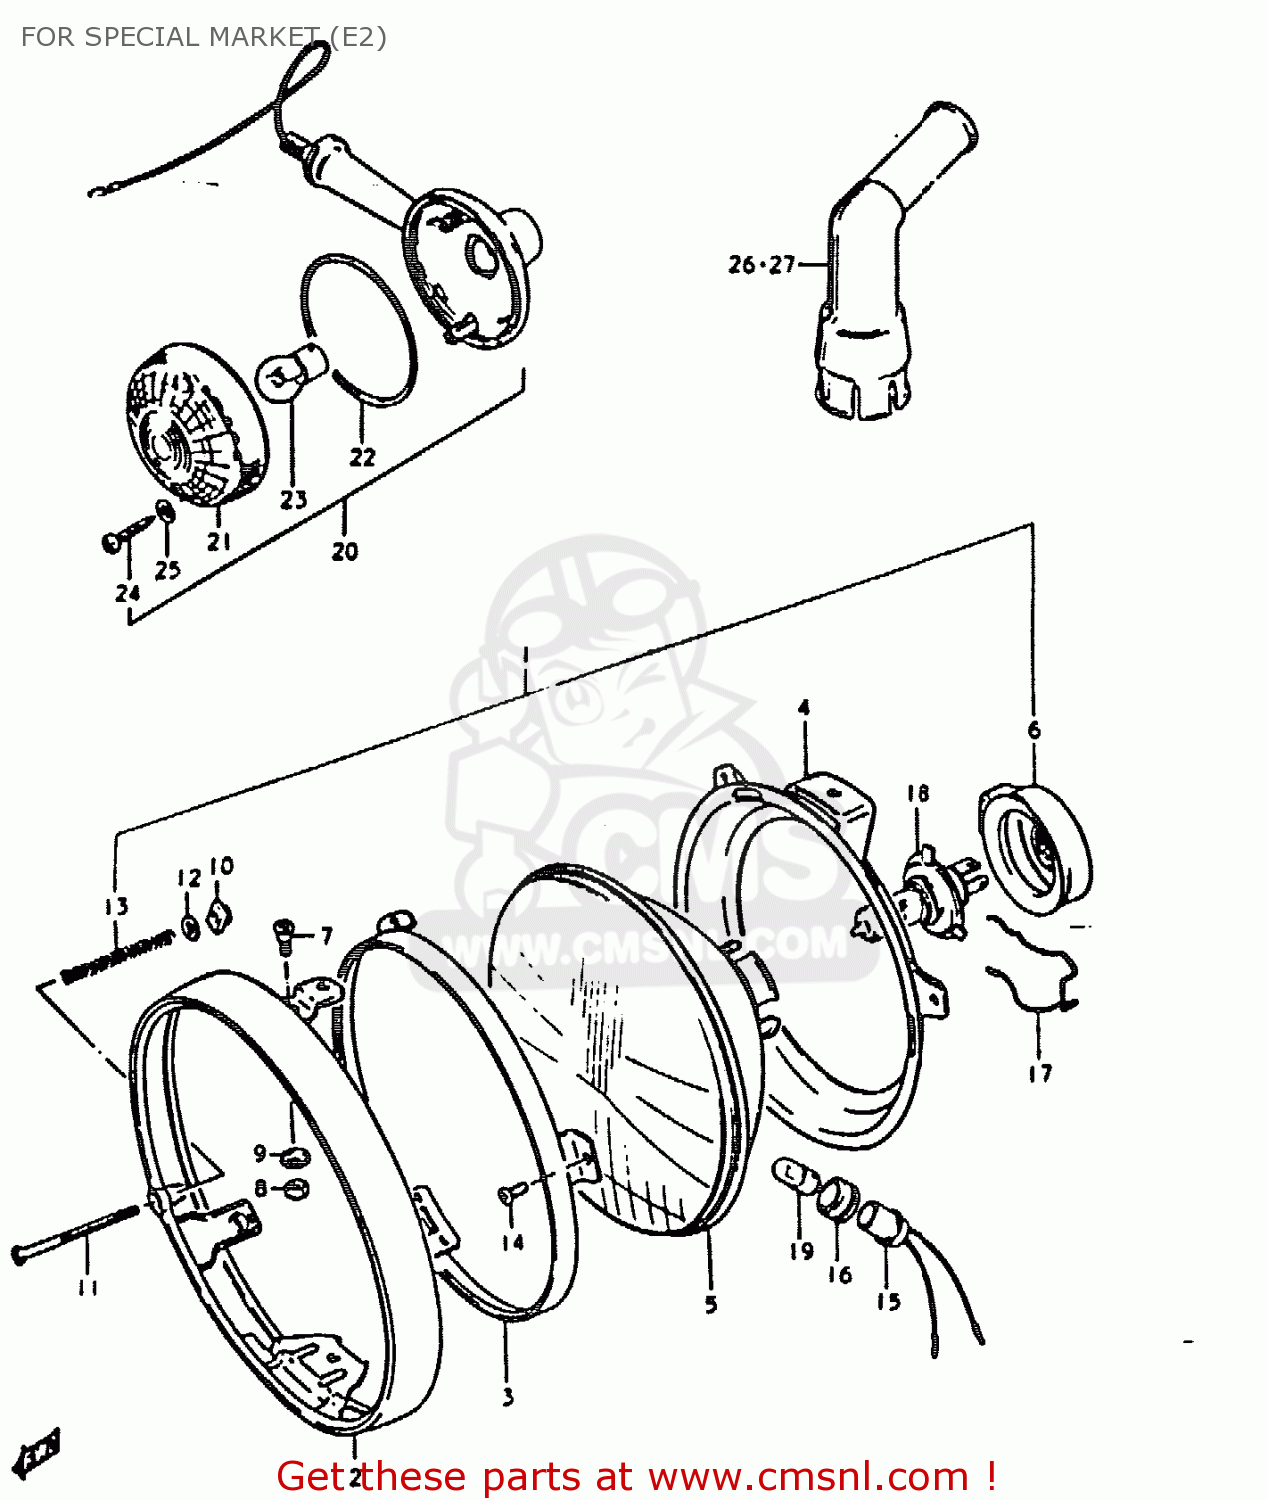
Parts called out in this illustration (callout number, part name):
1	HEADLAMP ASSY
2	RIM
3	RETAINER
4	RING,HEADLAMP UNIT
5	UNIT
6	COVER,HEADLAMP SOCKET
7	SCREW
8	NUT,ADJUSTING
9	SPACER
10	NUT
11	SCREW,HEADLAMP ADJUST
12	WASHER
13	SPRING,HEADLAMP ADJUST
14	SCREW
15	SOCKET
16	JOINT,RUBBER
17	CLAMP,HEADLAMP SOCKET
18	BULB(12V60/55W,H4)
19	BULB(12V4W)
20	LAMP ASSY, FRONT TURN SIGNAL
21	LENS
22	GASKET (NAS)
23	BULB 12V 21W
24	BOLT
25	GASKET (NAS)
26	CAP, SPARK PLUG (S)
27	CAP,SPARK PLUG
